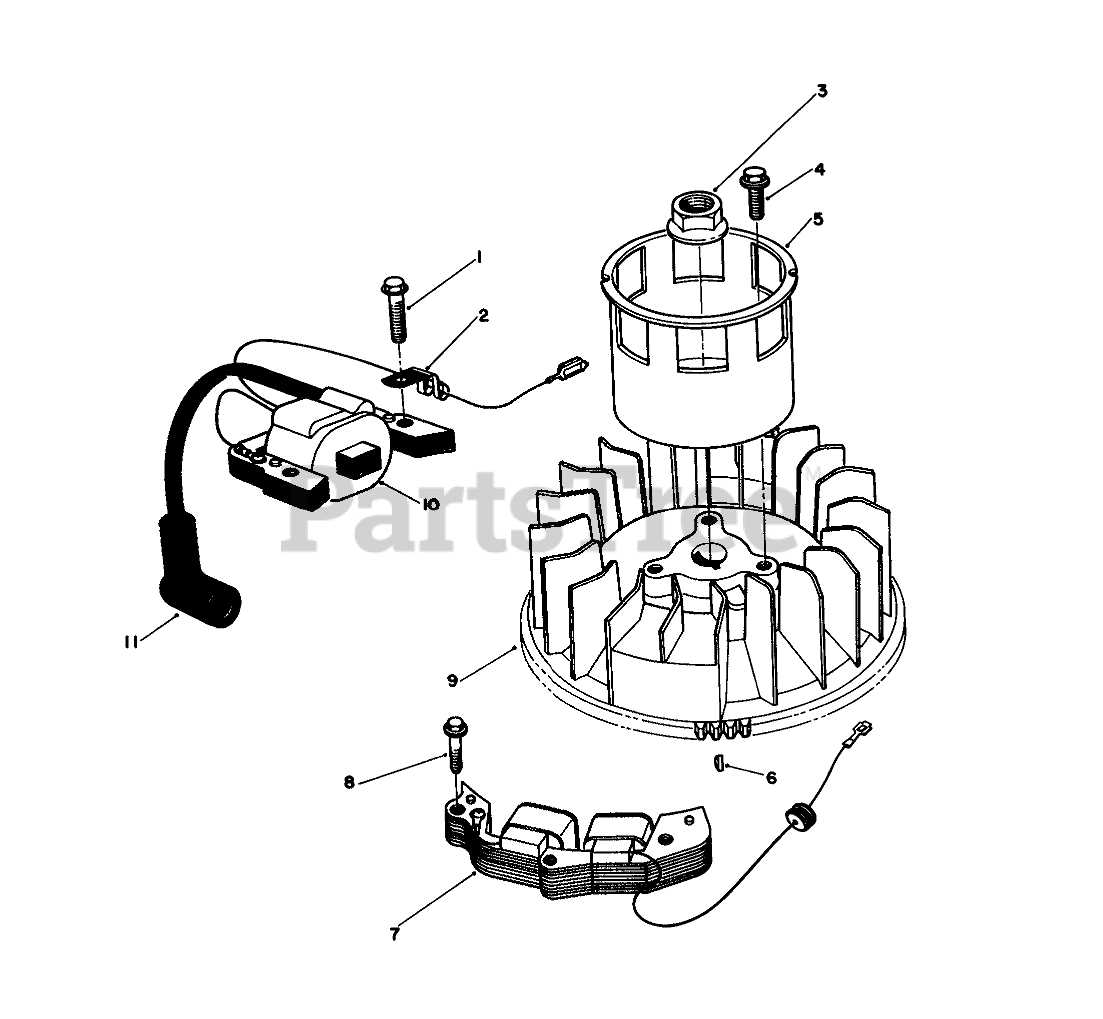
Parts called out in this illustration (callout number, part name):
2	CLAMP
9	FLYWHEEL
10	COIL
11	COVER
